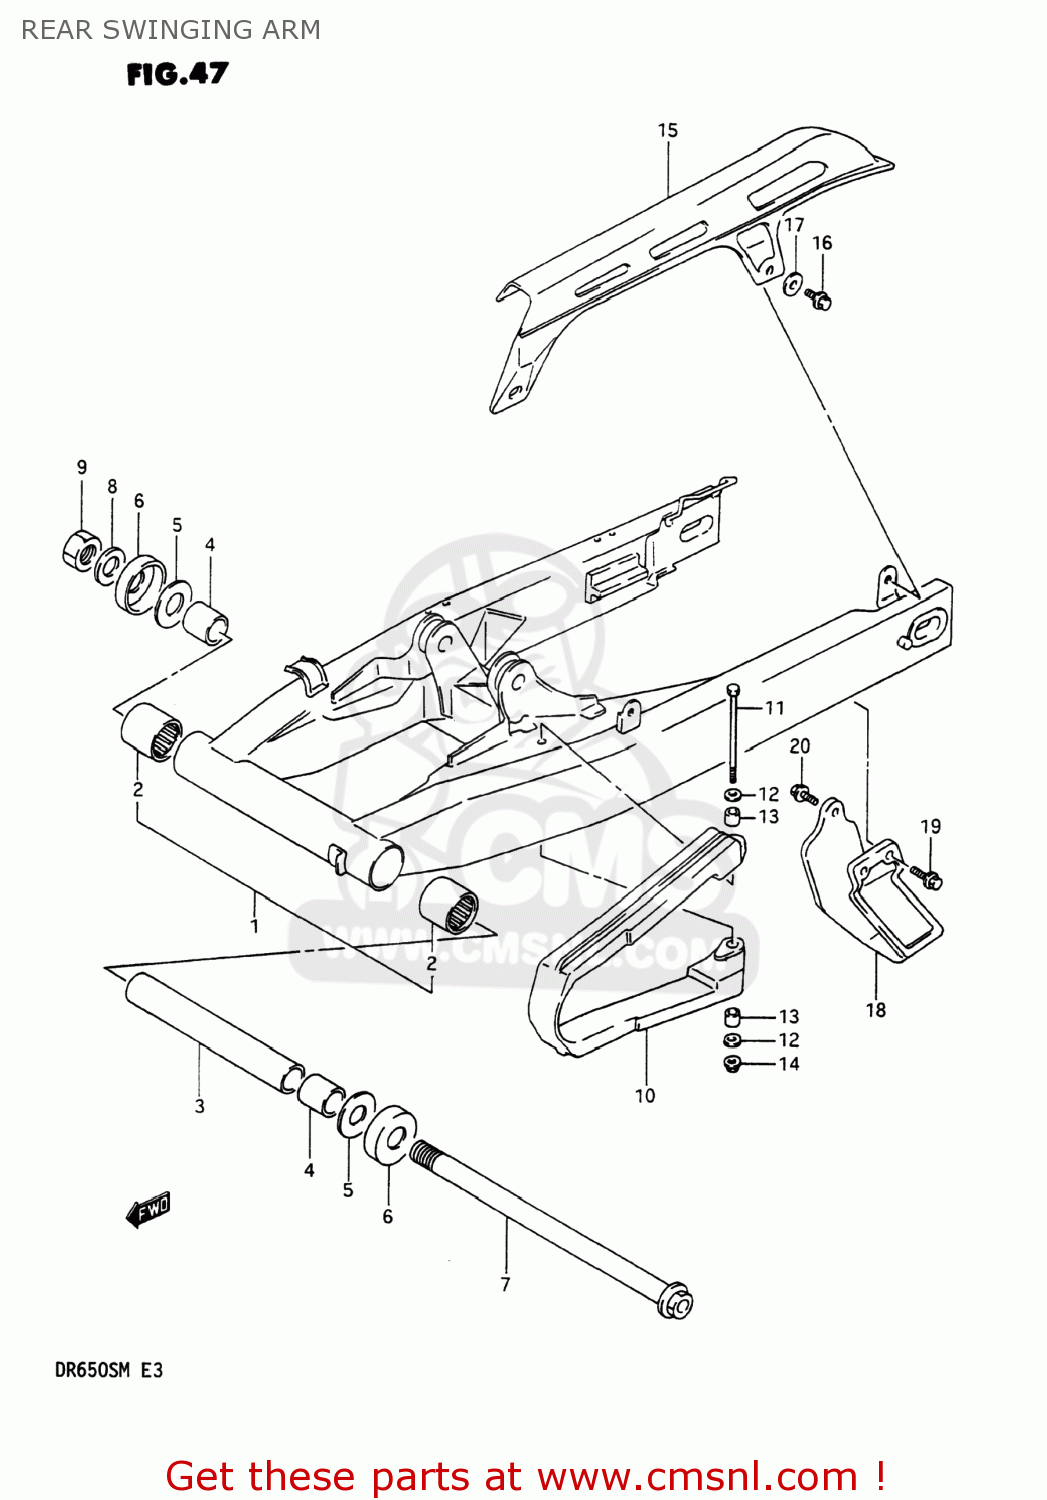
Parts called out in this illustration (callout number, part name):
1	SWING ARM ASSEMBLY,REAR
2	BEARING(22X29X20)
3	SPACER,RR SWGARM PIVOT CTR
4	SPACER,RR SWGARM PIVOT
5	WASHER
6	SEAL,RR SWGARM PIVOT DUST
7	SHAFT,REAR SWING ARM
8	WASHER (BLACK)
9	NUT (BLACK)
10	BUFFER,CHAIN TOUCH DEFLECTOR
11	BOLT,TOUCH DEFENSE FTG
12	WASHER (5.5X14X1.2)
13	SPACER (6.6X9X6.5)
14	NUT
15	CASE,CHAIN
16	BOLT
17	WASHER
18	GUIDE,CHAIN
19	BOLT
20	BOLT 6X16
